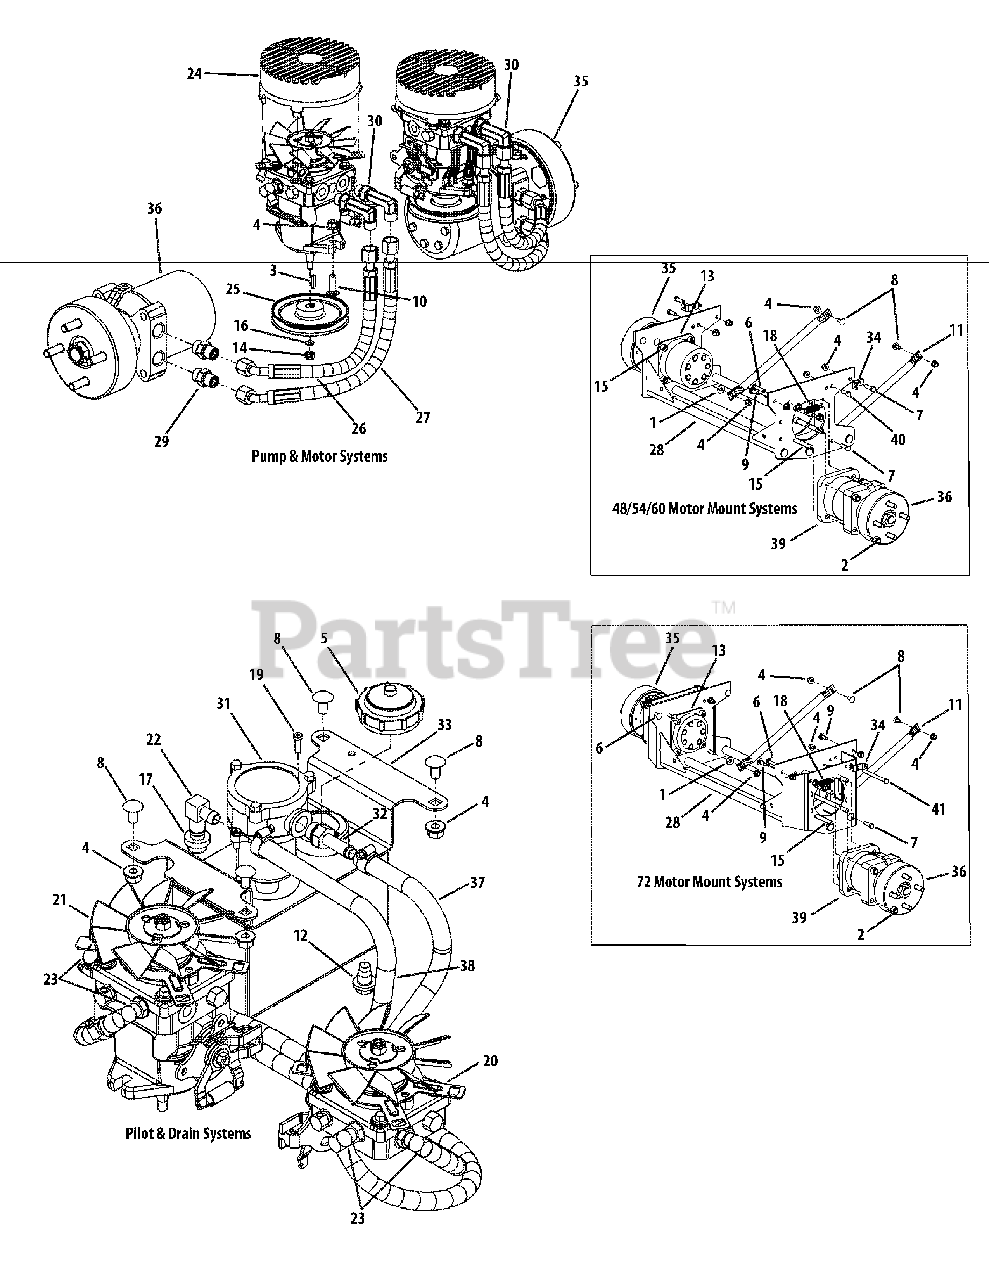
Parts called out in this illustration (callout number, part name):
1	Idler Washer
2	Washer lock 3/8 zinc
3	Key, 3/16" x 7/8"
4	Flange Lock Hex Nut, 3/8-16
5	Cap, Hydro Oil Tank
6	Hex Carriage Screw, 3/8-16, 1.75
6	Hex Carriage Screw, 3/8-16, 5.00
7	Hex Cap Screw, 3/8 -16 x 1.25
8	Carriage Bolt, 3/8-16 x .75 LG.
9	Carriage Bolt, 3/8-16 x 1
10	Carriage Screw, 3/8-16 x 1.25
12	Oil Pan Drain Plug w/ Seal
13	Hydro Wheel Motor Backup Plate
14	Hex Nut, 3/8-24
15	Socket Head Cap Screw, 1/2-13; 3-1/2
15	Socket Head Screw, 1/2-13; 6-1/2
16	Flat Washer, 3/8
17	Grommet Fitting, .54 ID x .78 OD
18	Spring Extension, .740 OD x 2.656
19	Head Cap Screw, 1/4-20 x 0.75
20	Hydro Pump, BDP-12, RH
20	Kit, Fan
21	Hydro Pump, BDP-12, LH
21	Kit, Fan
22	Fitting Elbow Spur, 5/8 x 1/2
23	Fitting Elbow, 9/16 x 1/2
24	Fan Pump Shroud
25	Hydro Pump Pulley
26	Short Pressure Hose Assembly
27	Long Pressure Hose Assembly
28	Hydro Motor Frame Assembly
29	Adaptor Fitting, 8 x 10
30	Adaptor, 8 x 8
31	Hydraulic In-Tank Filter includes:
31	Replacement Filter
32	Fitting, 3/4 ORB x 1/2 Tube
33	Hydraulic Tank Assembly
34	Rear Cable Mounting Bracket
35	Hydro Motor, LH Assembly
36	Hydro Motor, RH Assembly
37	Hose Assembly, Pilot inlcudes:
37	Tee Fitting, 1/2
37	Hose Clamp, 1/2
37	Fuel Hose, .50 ID x .75 OD (in inches)
38	Hose Assembly, Drain inlcudes:
38	Tee Fitting, 1/2
38	Hose Clamp, 1/2
38	Fuel Hose, .50 ID x .75 OD (in inches)
39	Spacer, Hydro, Wheel Motor
40	Hex Cap Screw, 3/8-16 x 1.00
41	Hex Cap Screw, 3/8-16 x 4.50
